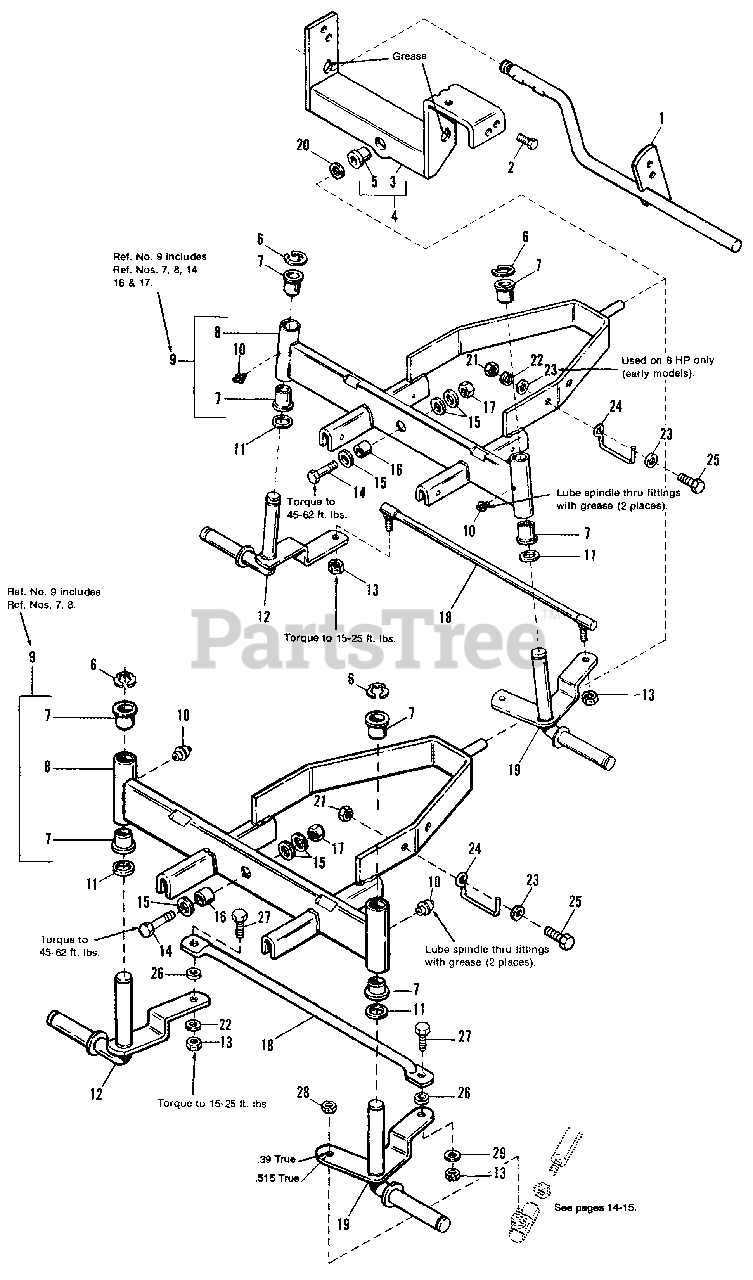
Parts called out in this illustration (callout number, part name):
1	LEVER ASSY., Brake
2	SCREW, Taptite, 5/16-18 x 3/4
4	SUPPORT ASSY., Rear (Incl. Ref. No. 5)
6	* E-RING, Ext., 3/4
6	** KLIPRING, Ext., 3/4
9	* AXLE ASSY., Front (Incl. Ref. Nos. 7, 8, 14, 16 & 17)
9	** AXLE ASSY., Front (Incl. Ref. Nos. 7 & 8)
10	FITTING, Lube, Drive Type
11	WASHER
12	* SPINDLE ASSY., R.H. (8 HP)
12	* SPINDLE ASSY., R.H. (11 & 12 HP)
12	** SPINDLE ASSY., R.H. (8 & 10 HP)
12	** SPINDLE ASSY., R.H. (12 HP)
13	* LOCKNUT, Hex, 3/8-24
13	** LOCKNUT, Hex, 3/8-16
14	CAPSCREW, Hex, 1/2-13 x 1-3/4 (Gr. 8)
15	WASHER (Qty. 2 on 12 HP)
16	SPACER
17	LOCKNUT, Hex, 1/2-13 (Early Models)
17	LOCKNUT, Hex Flange Lock, 1/2-13 (Later Models)
18	TIE ROD ASSEMBLY, Flattened End
18	TIE ROD ASSEMBLY, Ball Joint Type
19	* SPINDLE ASSY., L.H. (8 HP)
19	* SPINDLE ASSY., L.H. (11 & 12 HP)
19	** SPINDLE ASSY., L.H., .39 True Hole Drag Link (8 & 10 HP)
19	** SPINDLE ASSY., L.H., .39 True Hole Drag Link (12 HP)
19	** SPINDLE ASSY., L.H., .515 True Hole Drag Link (10 HP)
19	** SPINDLE ASSY., L.H., .515 True Hole Drag Link (12 HP)
20	WASHER, 5/8
21	NUT, Hex, 5/16-18
22	LOCKWASHER, 5/16 (Ealry Models)
22	WASHER, 3/8
23	WASHER, 5/16 (Qty. 1 on 11 & 12 HP)
24	GUIDE, Drag Link
25	CAPSCREW, Hex Hd., 5/16-18 x 1
27	CAPSCREW, 3/8-16 x 1
28	LOCKNUT, Center 3/8-24 (Use with .39" True Hole in L.H. Spin
28	LOCKNUT, Center, 1/2-20 (Use with .515" True Hole in L.H. Sp
